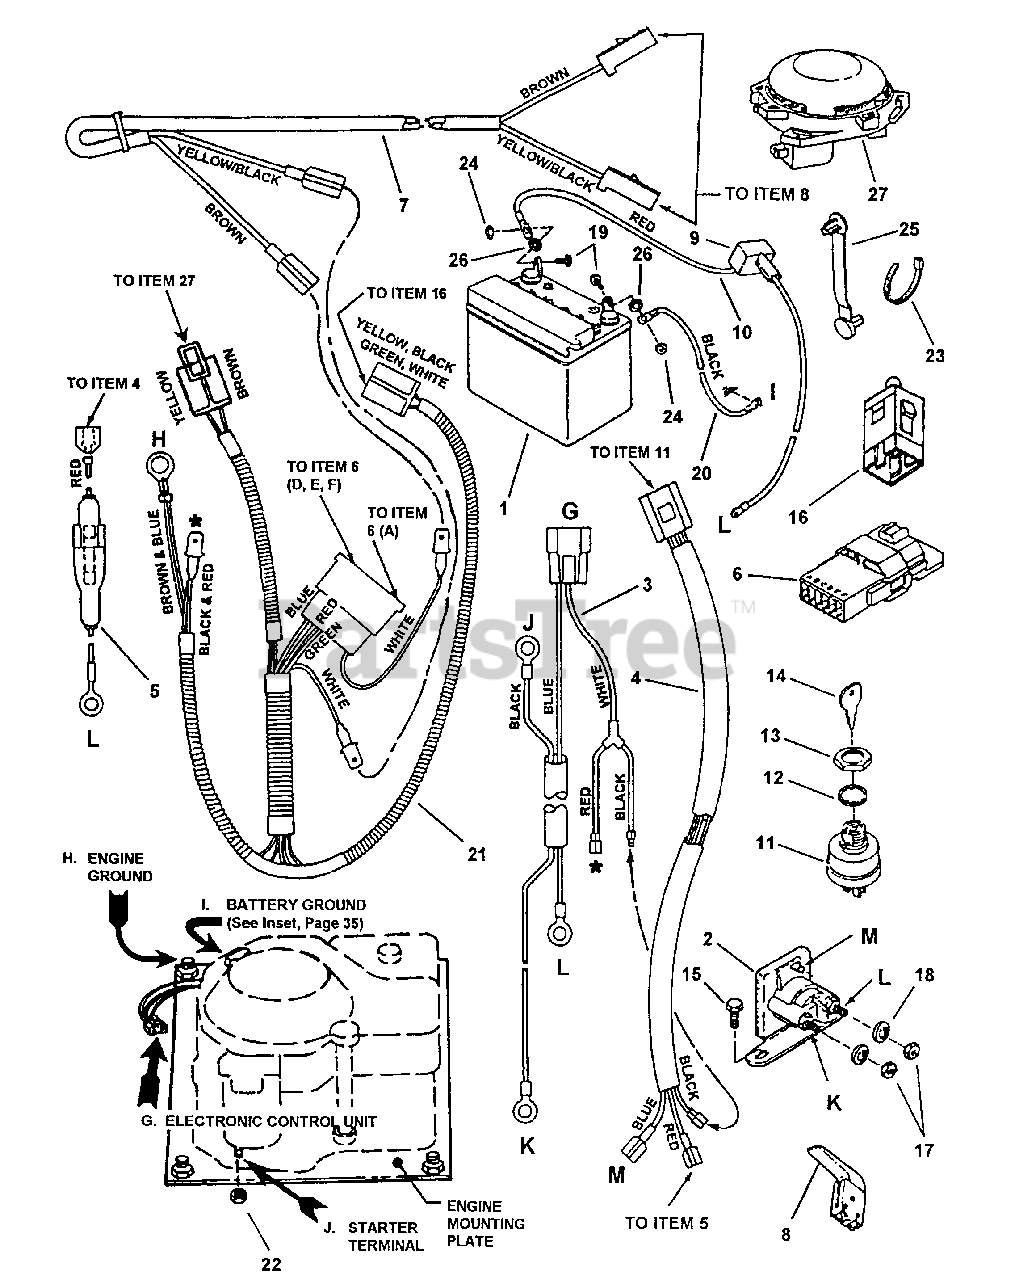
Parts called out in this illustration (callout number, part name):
1	KIT, 12V Dry Charge Battery
2	SOLENOID
3	HARNESS, Starter Wiring
4	HARNESS, Ignition Wiring
5	HOLDER, Fuse
6	INTERLOCK Module
7	HARNESS, (Deck Interlock Wiring)
8	SWITCH, Deck Interlock (NO)
9	COVER, Battery Cable
10	CABLE, Positive (Red) (17" Long)
11	SWITCH, Ignition (Includes keys #11138)
12	WASHER, 5/8" Internal Tooth Lock
13	NUT, 5/8-32 Hex
14	KEY, Switch
15	SCREW, 1/4-20 x 1/2" Hex Washer Self-Tap
16	SWITCH, Operator Presence Control (OPC)Traction (NC/NO)
17	NUT, 1/4-20 Hex, Grade 5 or B
18	WASHER, 1/4" Internal Tooth Lock
19	SCREW, 1/4-20 x 5/8" Hex Head Cap, Grade 5
20	CABLE, Negative (15")
21	HARNESS, Operator Presence Control Wire
22	NUT, 1/4-20 Hex, Grade 5 or B
23	TIE, 7" Long Cable
24	NUT, 1/4-20 Hex Center Lock, Grade 5 or B
25	TIE, 2" Long Cable
26	RETAINER, 1/4" Bolt
27	SWITCH, Seat (NC)
